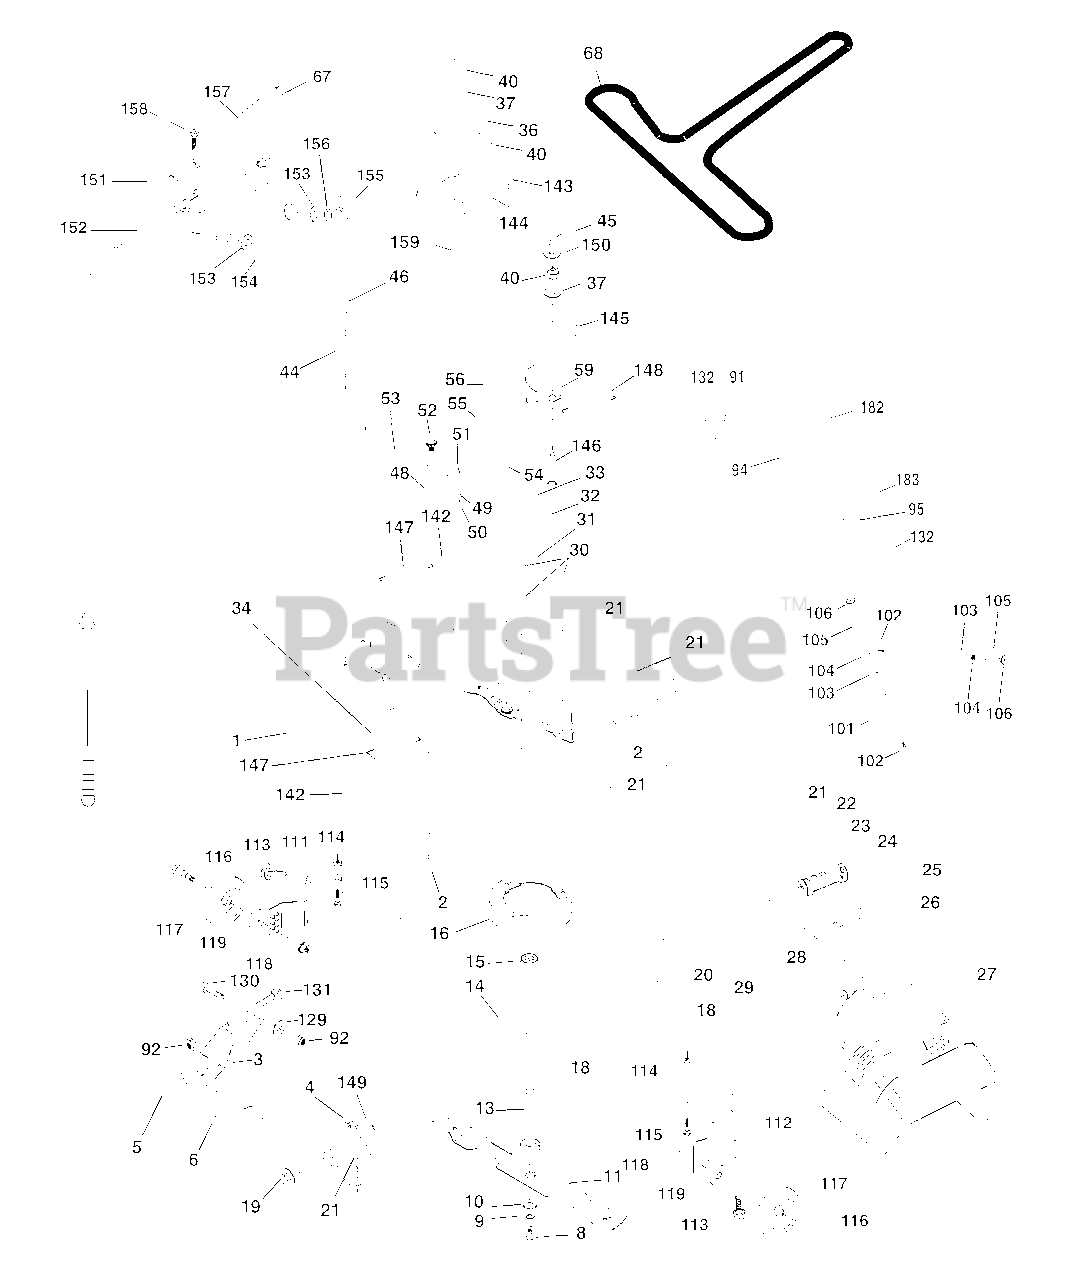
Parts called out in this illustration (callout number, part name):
1	Mower Deck Assembly, 42"
2	Bolt
3	Bracket Asm Fr. Sway Bar 3/42
4	Bracket Asm Deck 42" Sway Bar
5	Retainer Spring
6	Bar Sway Deck
8	Bolt 3/8-24 x 25 Grade 8 patched
9	Washer, Lock
10	Washer, Hardened
11	Blade, Mulching 42" Std
11	Blade Mower 42" Hi-Lift Std
13	Shaft Assembly, Mandrel, Vented
14	Housing, Mandrel, Vented
15	Bearing, Ball, Mandrel
16	Stripper, Mandrel Deck
18	Bolt, Carriage 5/16-18 x 5/8
19	Bolt, Shoulder
20	Baffle, Vortex
21	Nut
22	Stiffener Bracket
23	Bracket, Deflector Mower 42"
24	Cap, Sleeve 80 x 112 Blk Mower
25	Spring, Torsion, Deflector 2 52
26	Nut, Push Phos & Oil
27	Shield, Deflector 42" Blk
28	Washer 11/32 x 5/8 x 16 Gauge
29	Rod, Hinge 42" 6 75 W/G
30	Screw Thdrol
31	Washer, Spacer Mower Vented
32	Pulley, Mandrel
33	Nut, Toplock
34	Bolt
36	Pulley, Idler, Flat
37	Washer 13/32 x 13/16 x 16 Gauge
40	Nut
44	Guard, Mandrel, LH
45	Retainer
46	Screw, Thdrol 1/4-20 x 5/8 T
48	Washer, Hardened
49	Roller Assembly, Cam Follower
50	Bolt, Shoulder #10-24 Grade 5
51	Locknut
52	Bolt, Shoulder 5/16-18 UNC
53	Arm Assembly, Pad, Brake
54	Washer, Hardened
55	Arm, Idler
56	Spacer, Retainer
59	Guard TUV Idler
67	Knob Round
68	V-Belt, 42" Mower
91	Bracket Asm Noseroller LH
94	Roller Nose 38 & 42
95	Bracket Asm Noseroller RH
101	Mulcher Cover
102	Screw, Pan Hd Phillip 10-24 x 5/8
103	Washer, Flat
104	Washer, Lock
105	Latch Assembly
106	Nut, Weld
111	Bracket, Gauge, Wheel LH
112	Bracket, Gauge, Wheel RH
113	Screw 3/8-16 x .625
114	Bolt Carr. 5/16-18 x 5/8
115	Nut Keps 5/16-18 UNC
116	Bolt, Shoulder
117	Wheel, Gauge
118	Nut Centerlock 3/8-16
119	Washer 3/8 x 7/8 x 14 Ga.
132	Screw 3/8-16 x .75
142	Arm Spring Brake Mower
143	Bracket Arm Idler 42"
144	Keeper Belt 42" Clutch Cable
145	Pulley Idler Flat
146	Bolt Carriage Idler
147	Spring Extension
148	Spring Return Idler
149	Retainer Spring Yellow
150	Washer 9/32 x 3/4 x 16 Ga.
151	Bracket Clutch Cable
152	Clutch Cable 42"
153	Washer Flat 3/8" Type B
154	Spring Retainer
155	Spring Retention LVR CLTCH CAB
156	Spacer Clutch Cable
157	Rod Clutch Cable 3/8"
158	Screw Hex Thd Cut 1/4-20 x 5/8
159	Bolt Rdhd Sqn 3/8-16 UNC x 1-3/4
182	Rod Roller Nose
183	Retainer Spring
